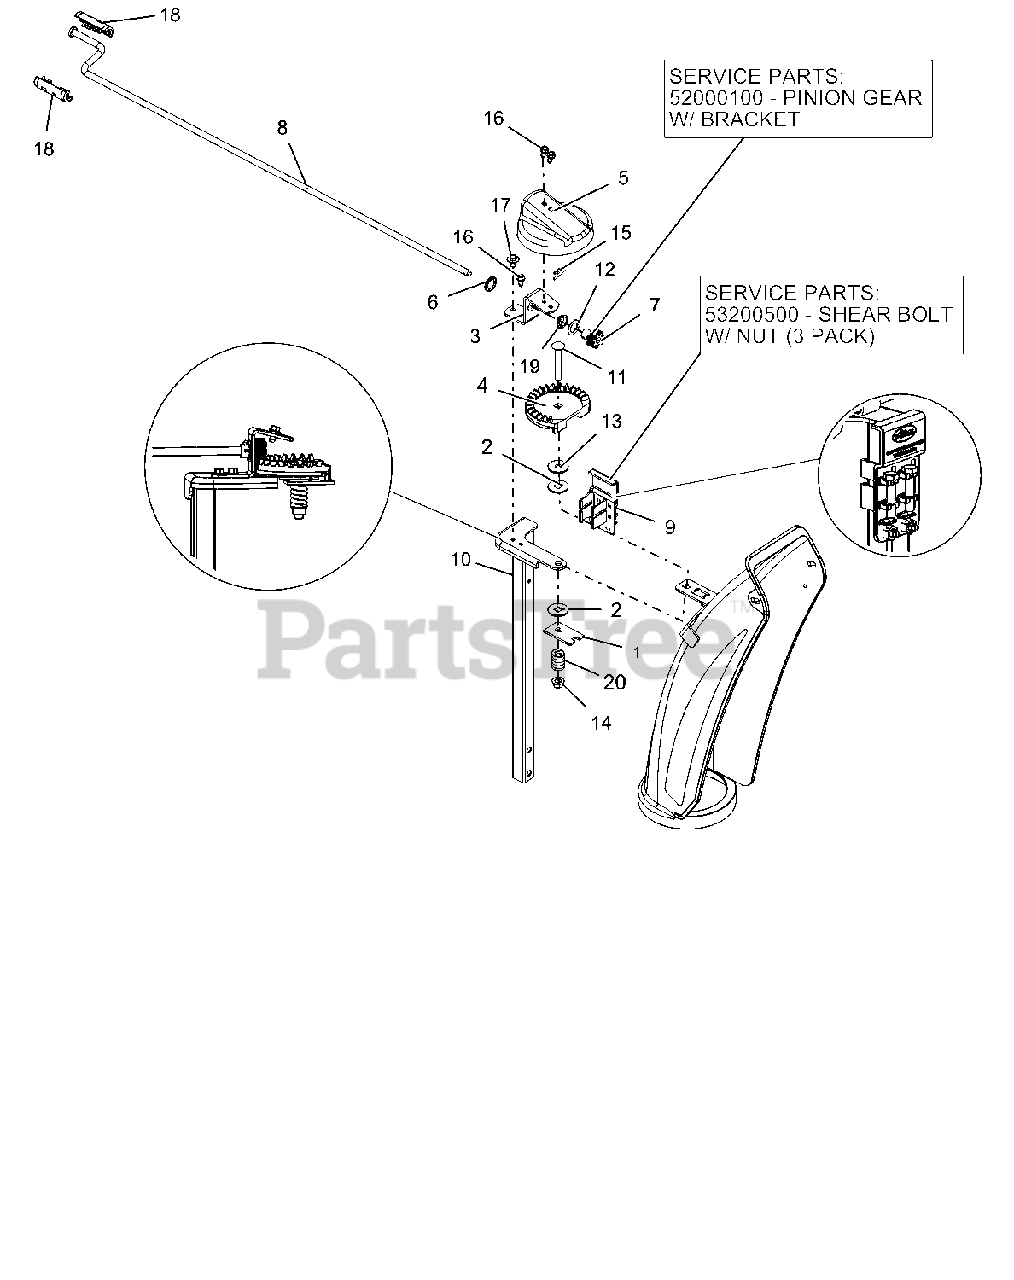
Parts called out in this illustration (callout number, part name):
1	PLATE, FRICTION
2	FRICTION WASHER
3	BRACKET, PINION GEAR
4	CHUTE GEAR
5	GEAR COVER
6	PUSHNUT .625
7	PINION GEAR - CHUTE
8	ROD, CHUTE CRANK, COMP&SNOTEK
9	HOLDER W SMALL SHEAR BOLT /NUT
10	CHUTE PEDESTAL, TALL COMPACT
11	@BLT-RDHDSQNK .38-16X2.50 G5YZ
12	WSHR-THRST .625 X 1.0 X .03
13	@WSHR-FL-STL .406X1.25X.10 ZC
14	@NUT-LK-TOP-FLG .38-16 YWZC
15	PIN, SPRING CLIP
16	SCR-TAP .25-20X.50 HWH TR YWZ
17	SCR-TAP .25-20X.50 LGHWH TR YZ
18	KNOB, CHUTE CRANK - SNAP BLK
19	BUSHING, POLYLINER-.63 SNAPIN
20	SG-COMP .187X.56X1.62
21	PINION GEAR W/BRACKET
22	SHEAR BOLT WITH NUT
